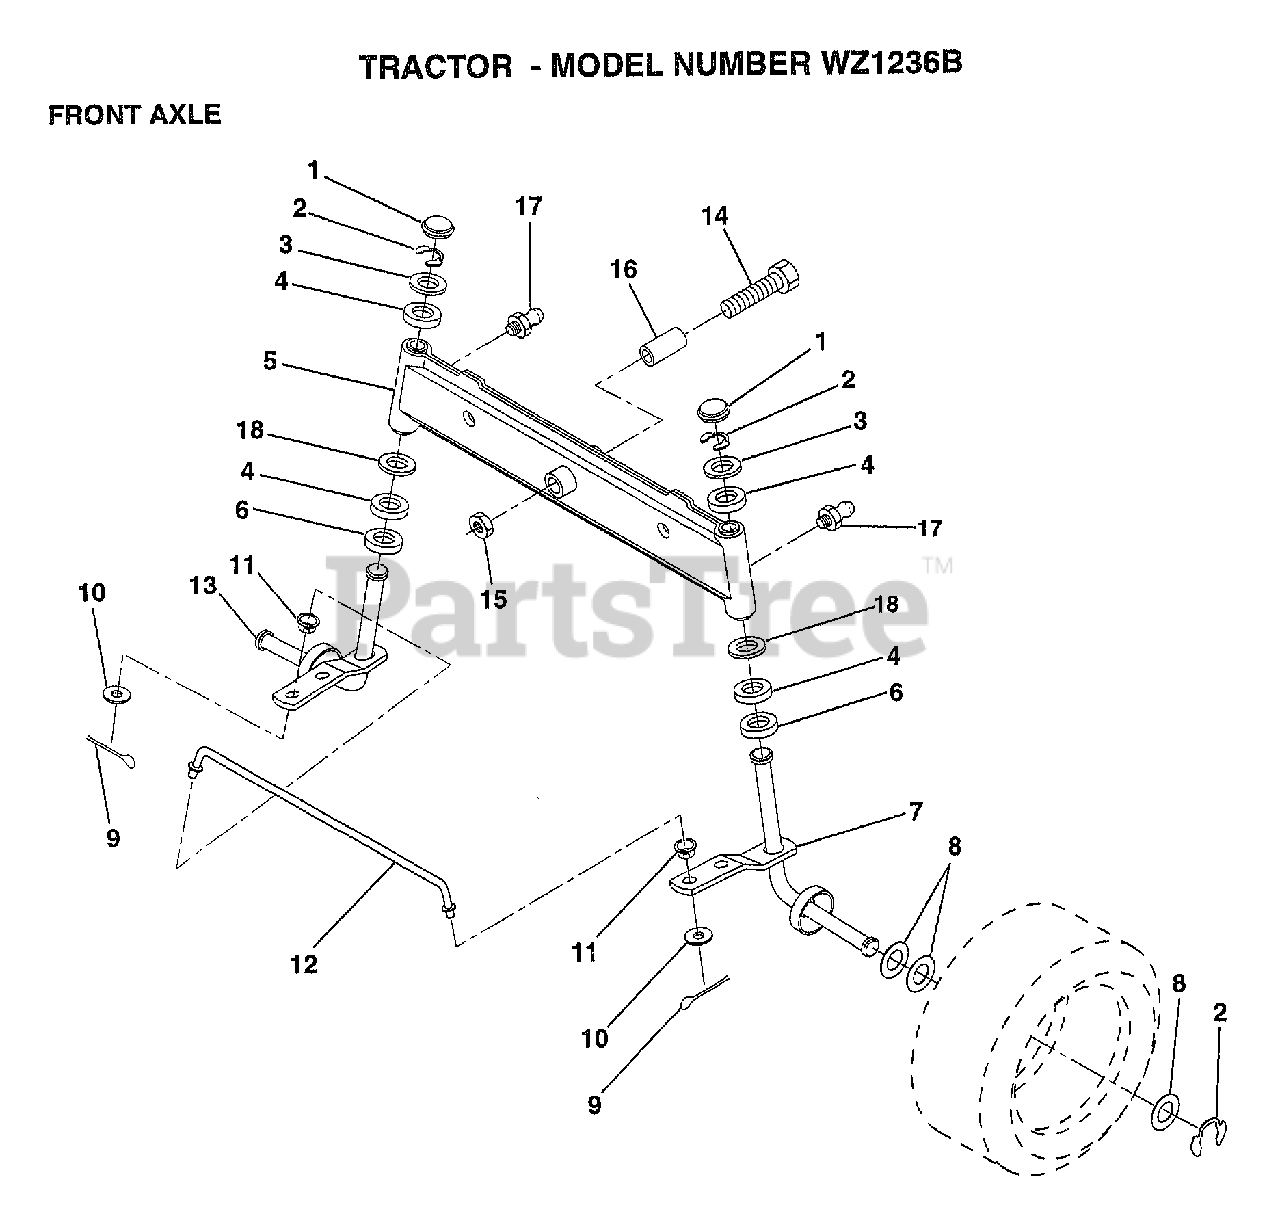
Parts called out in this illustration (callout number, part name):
1	CAP
2	RING
3	WASHER
4	COL. SRTG. BEAR.
5	AXLE ASM FRONT
6	WASHER .T
7	SPINDLE.ASSY.RH
8	WASHER
9	COTTER PIN
10	WASHER
11	BUSHING.DRAGLINK
12	TIE ROD
13	SPINDLE.ASSY.LH
14	BOLT HEX 5/8-11
15	"NUT-LOC,FLANGE LT"
16	BEARING
17	ZERK M
18	WASHER
